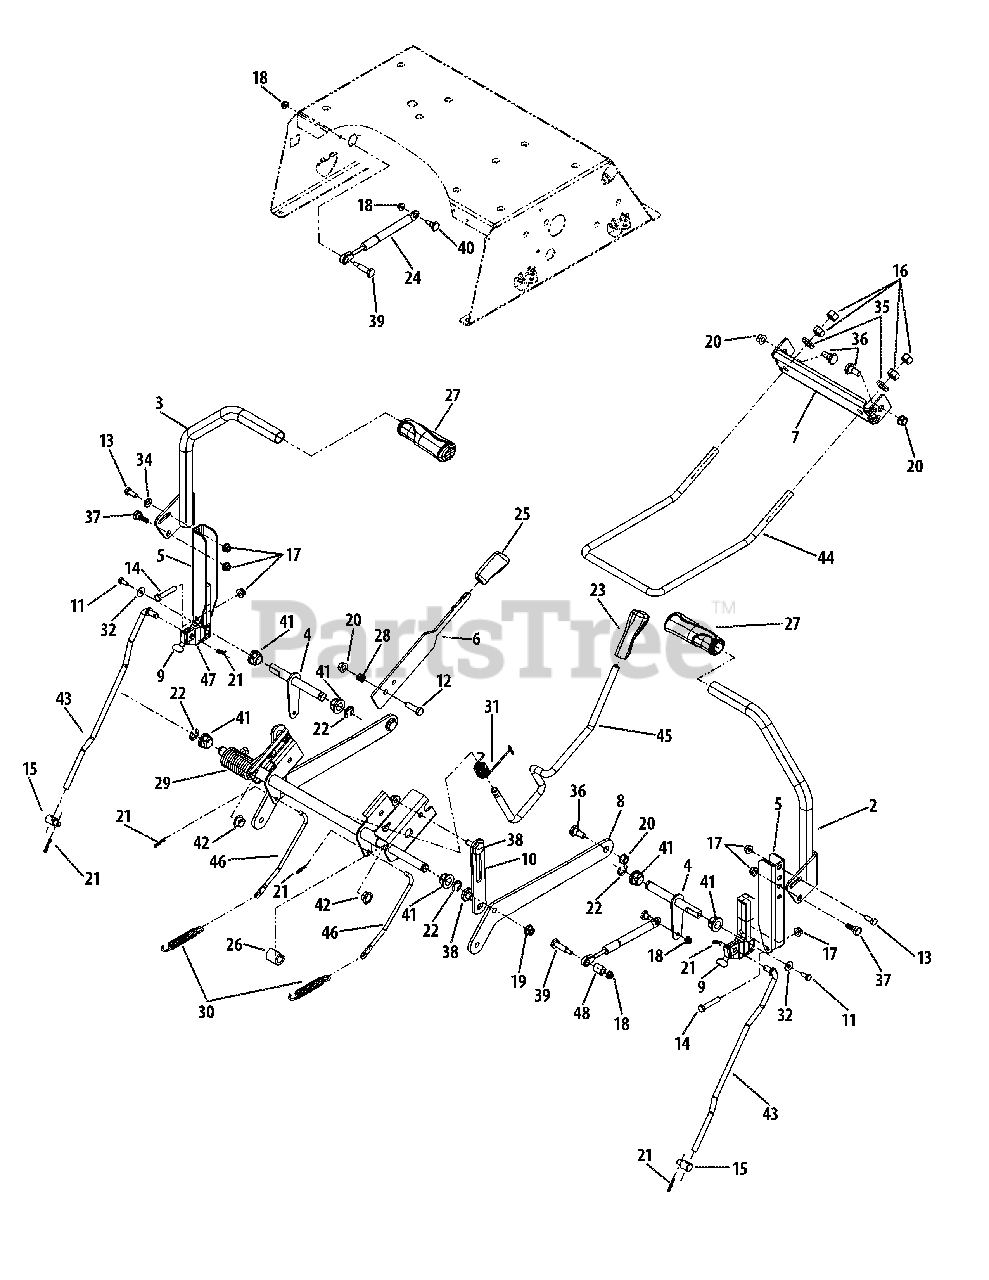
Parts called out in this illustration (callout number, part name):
4	Shaft Control
5	Lapbar Pivot Bracket
9	Actuator Bracket
11	Hex Screw, 1/4-20 x .625
12	Hex Screw, 3/8 -16 x 1.25
13	Hex Screw, 5/16-18 x .75
14	Hex Screw, 5/16-18 x 1.75
15	Ferrule, 3/8 -24 x .375
16	Hex Nut, 1/2-13
17	Flange Lock Nut, 5/16-18
18	Flange Lock Nut, 1/4-20
19	Flange Lock Nut, 3/8-16
20	Flange Lock Nut, 3/8-16
21	Cotter Pin, .072 x 1.13
22	E-Ring, .625
23	Handle Grip, 1/2
24	Damper Cylinder, .59 x 7.84
25	Handle Grip
26	Spacer, .621 x 1.00
27	Handle Grip, 1.0
28	Compression Spring, .50 x .50
29	Torsion Spring, .194
30	Extension Spring, .59 x 4.00
31	Spring, Torsion RZT
32	Bell Washer, .265 x .75 x .062
33	Flat Washer, .510 x 1.00 x.060
34	Flat Washer, .344 x .688 x .065
35	Flat Washer, .531 x 1.062 x .134
36	Shoulder Bolt, .496 x .336 x 3/8-16
37	Shoulder Screw, .437 x .268 x 5/16-18
38	Shoulder Screw, .500 x .434
39	Shoulder Screw, .374 x 1.16
40	Shoulder Screw, .375 x .380 x 1/4-20
41	Hex Flange Bearing
42	Flange Bearing, .626 x .938 x .344
43	Lapbar Control Rod
44	Deck Front Hanger Rod
45	Deck Lift Handle Rod
48	Spacer, .385 x .630 x .75
